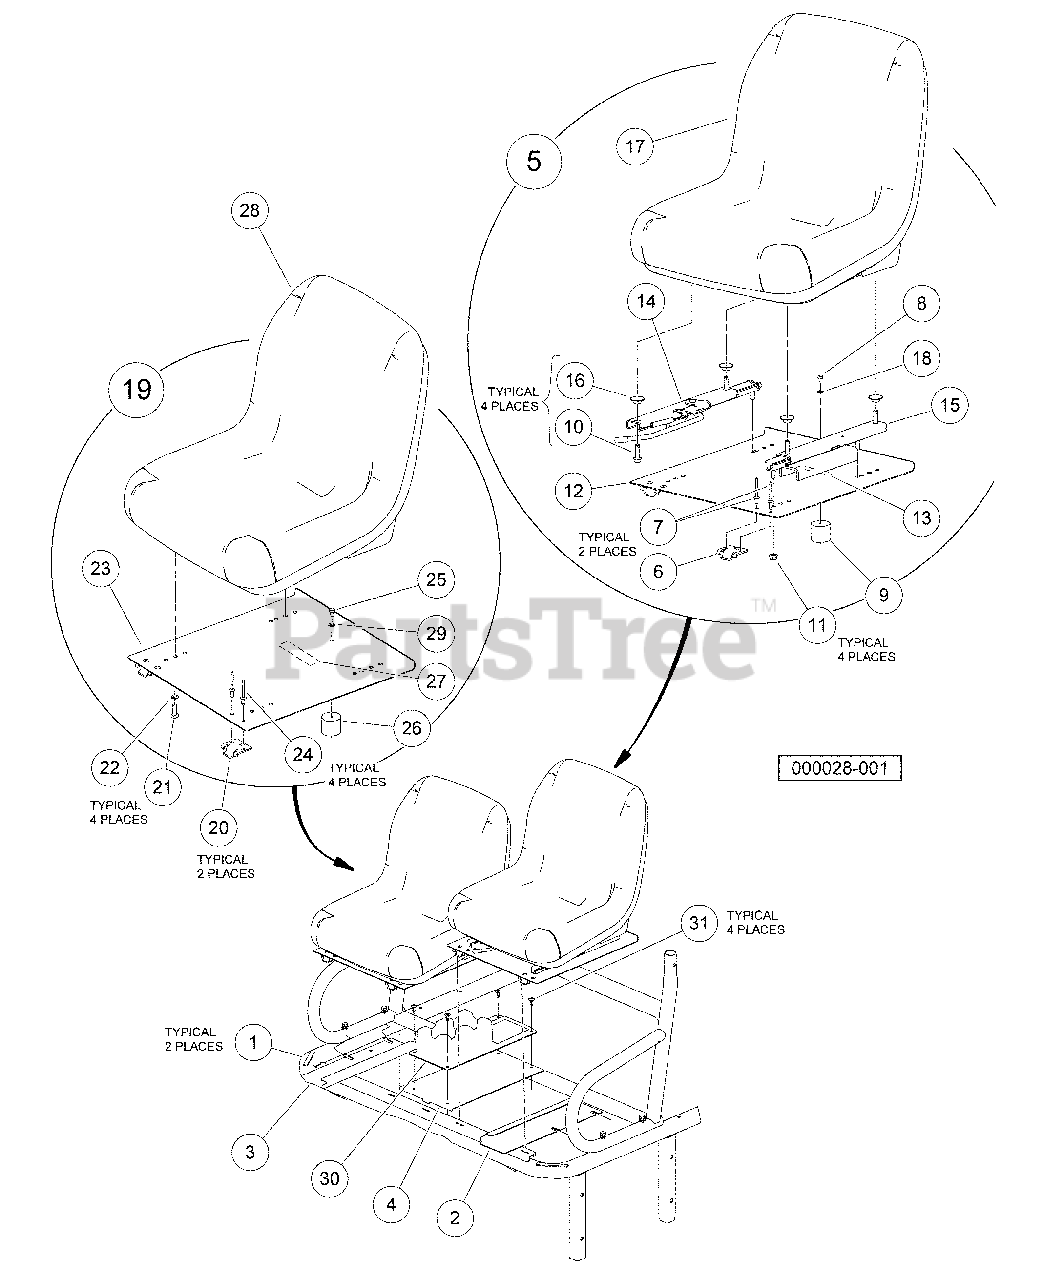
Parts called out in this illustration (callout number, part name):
1	Tape, Vinyl Foam 1/8" x 3/4"
2	Closeout, Driver Side
3	Closeout, Passenger Side
4	Pan, Center, Closeout
5	Asm, Bucket Seat Adjustable
6	Hinge Plate
7	Rivet, 1/4 X .438 Blind
8	Screw, 6m-1.00 X 10mm Hex Head
9	Seat Holder Cup
10	Bolt, Flange Head, M8 X 30.0
11	Nut,m8,all Metal Lock
12	Pan, Seat, Driver Asm
13	Decal, Hot Surface Warning
14	Adjuster, Forward/Aft
15	Adjuster, Slider
16	Washer, Bell
17	Seat, Bucket, Gray
18	Lockwasher, 1/4 Helical Split
19	Assembly, Bucket Seat w/Spacers
20	Hinge Plate
21	Screw, M8-125 X 22 Hex-Head
22	Lockwasher, 8mm Split
23	Pan, Seat, Passenger
24	Rivet, 1/4 X .438 Blind
25	Screw, 6m-1.00 X 10mm Hex Head
26	Seat Holder Cup
27	Decal, Hot Surface Warning
28	Seat, Bucket, Gray
29	Lockwasher, 1/4 Helical Split
30	Console, Center, Drink Holder
31	Rivet, Removable, Tuflok 1/4"
